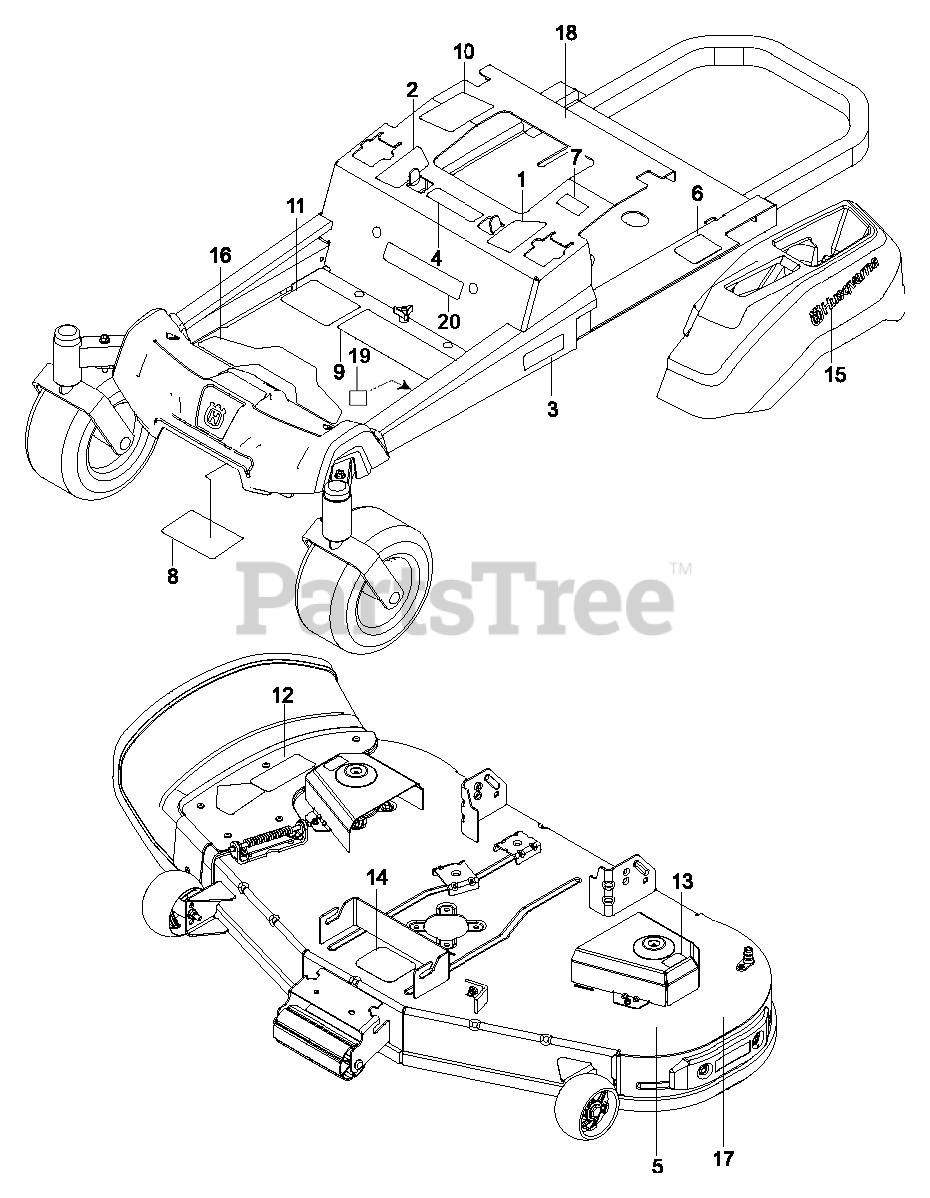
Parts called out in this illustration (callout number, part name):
1	DECAL.ZTR.RZ.THRTL/PRKBRK.V2.L
2	DECAL.ZTR.RZ.THRTL/PRKBRK.V2.R
3	DECAL.ZTR.SIDERAIL.MN.Z248F.HU
4	EURO DECAL-BATTERY WARNIN6
5	DECAL DECK DECAL DECAL.DECK.WA
5	DECAL.BADGE.55MM.CROWNH.HUSQ
6	DECAL, DO NOT TOW
7	DECAL, EXITING MOWER
8	DECAL, SERVICE
9	DECAL.ZTR.WARNING.SMARTIGNITIN
9	DECAL ZTR WARNING DECAL DECAL.
10	DECAL.WARNING.CUST.RESP.E85.
11	DECAL.ZTR.STARTINSTRCT.CHOKE15
12	DECAL.TRACT/ZTR.DECKWARN.HUSQ
13	DECAL.DECK.CLEARCUT.NOSTEP
14	DECAL, BELT ROUTING
15	DECAL.HUSQVARNA.210MM
16	PAD.RZ.FOOTREST.PLATE
17	DECAL DECK DECAL DECAL.48DECK.
17	DECAL.80.DBA.AUSTRALIA
18	DECAL ZTR BRAND GRAPHIC DECAL.
19	DECAL.80.DBA.AUSTRALIA
20	DECAL ZTR BRAND GRAPHIC DECAL.
